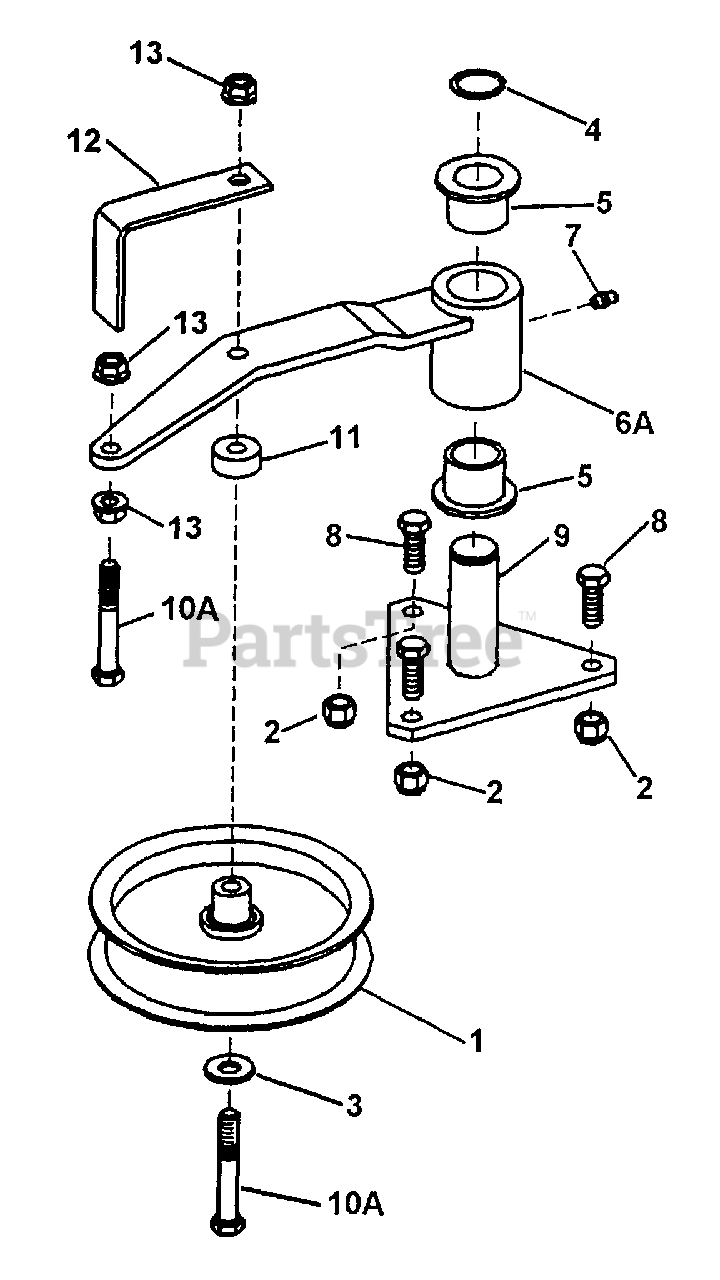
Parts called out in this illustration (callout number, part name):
1	PULLEY, Idler (5.00 O.D.)
2	NUT, 3/8-16 HEX NYLON LOCK
3	WASHER, 3/8" USS
4	RING, 1" Retaining
5	BUSHING
6A	IDLER ARM (32")
7	FITTING, Lube
8	BOLT, 3/8-16 X 1" GD5 CZ
9	PIVOT, Idler Arm
10A	BOLT, 3/8-16 X 2-1/2" GD5 CZ
11	BUSHING, .38" I.D. x 1" O.D. x .410"
12	RETAINER, Belt
13	NUT, 3/8-16 HEX SERRATED FLANGE
